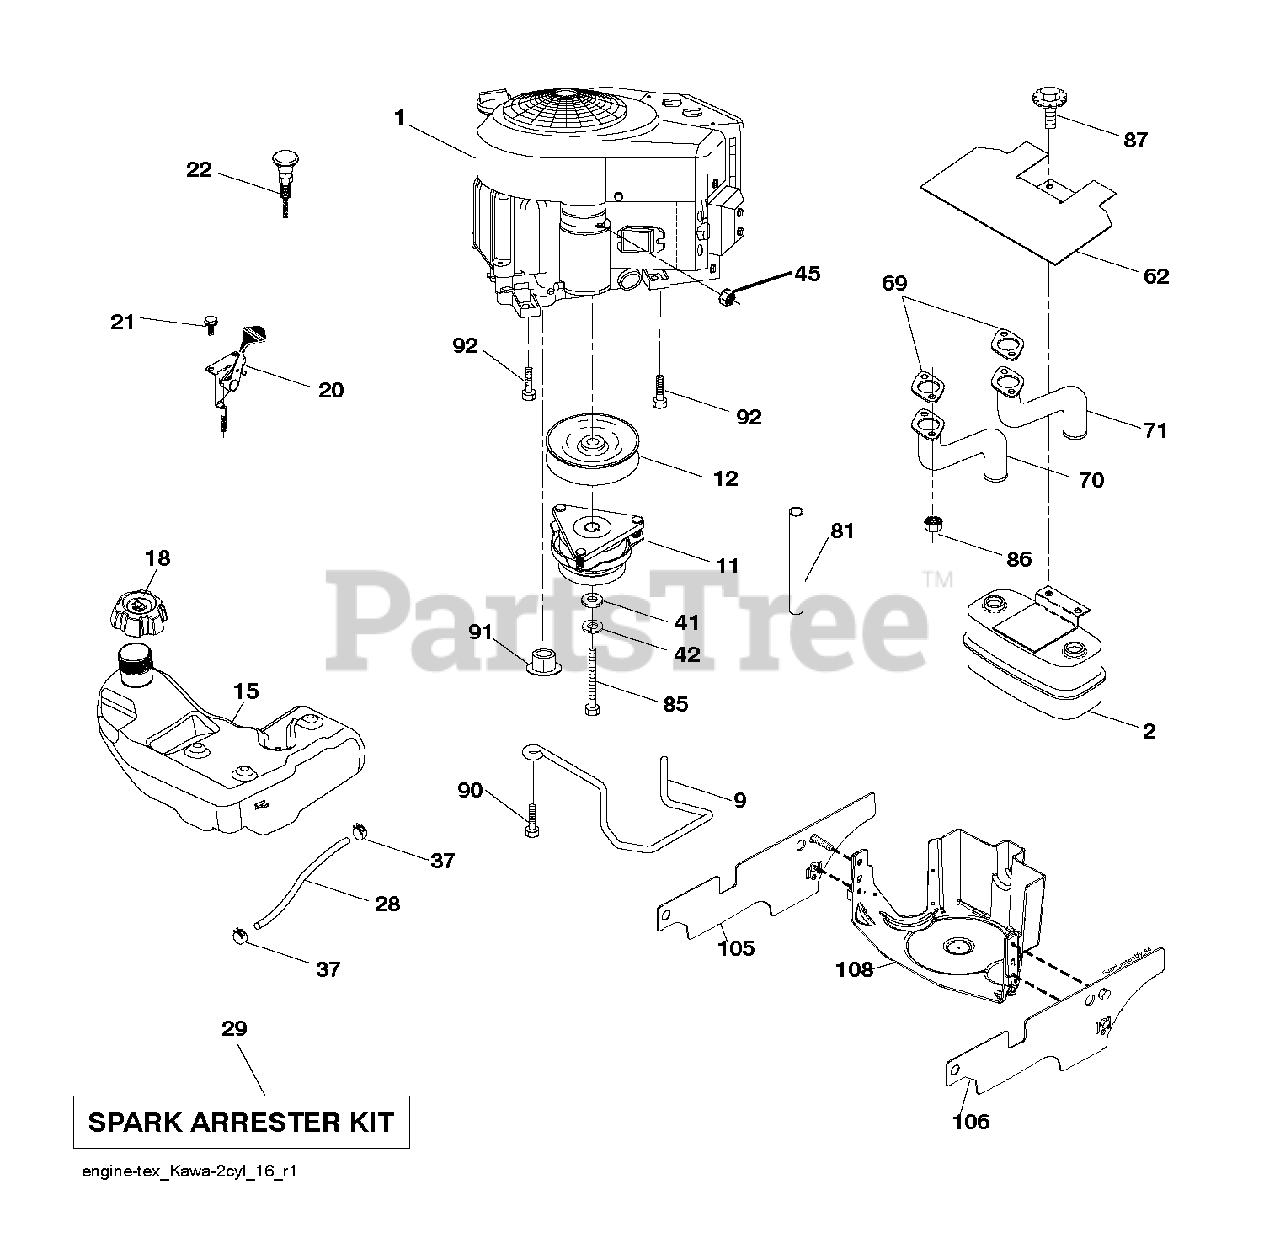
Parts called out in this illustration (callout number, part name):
2	MUFFLER.TWIN.CYL.LOW.TONE
9	KEEPER.BELT.ENGINE.4.2
11	RB.CLUTCH.OGURA.4.4.PD
12	PULLEY.ENGINE.TUFFTORQ
15	TANK.FUEL.4GAL
18	CAP.FL.R.3'N/CARB.H.CROWN.498
20	THROTTLE CABLE
21	SCREW.#10 X 0.750.BOS
22	CONTROL.CHOKE.ERGO.PUSH-IN.BLA
28	REPL BY 532 00 85-43
29	KIT.SPARK ARRESTOR 794945 B&S
37	HOSE CLAMP
42	LOCKWASHER
45	NUT
62	SHIELD.HEAT.MUFFLER
70	TUBE.EXHAUST.LH.FR961/FR730
71	TUBE.EXHAUST.RH.FR961/FR730
81	TUBE, DRAIN OIL ASM.
85	BOLT HEX 7/16-20X4-1/4"
86	NUT.HEX.FLANGE.TOPLOCK
87	BOLT, 5/16-18 X 1 3/4
90	SCREW 3/8-16X1
91	BUSHING.1.375OD
92	SCREW 3/8-16X1
108	ENGINE COVER
